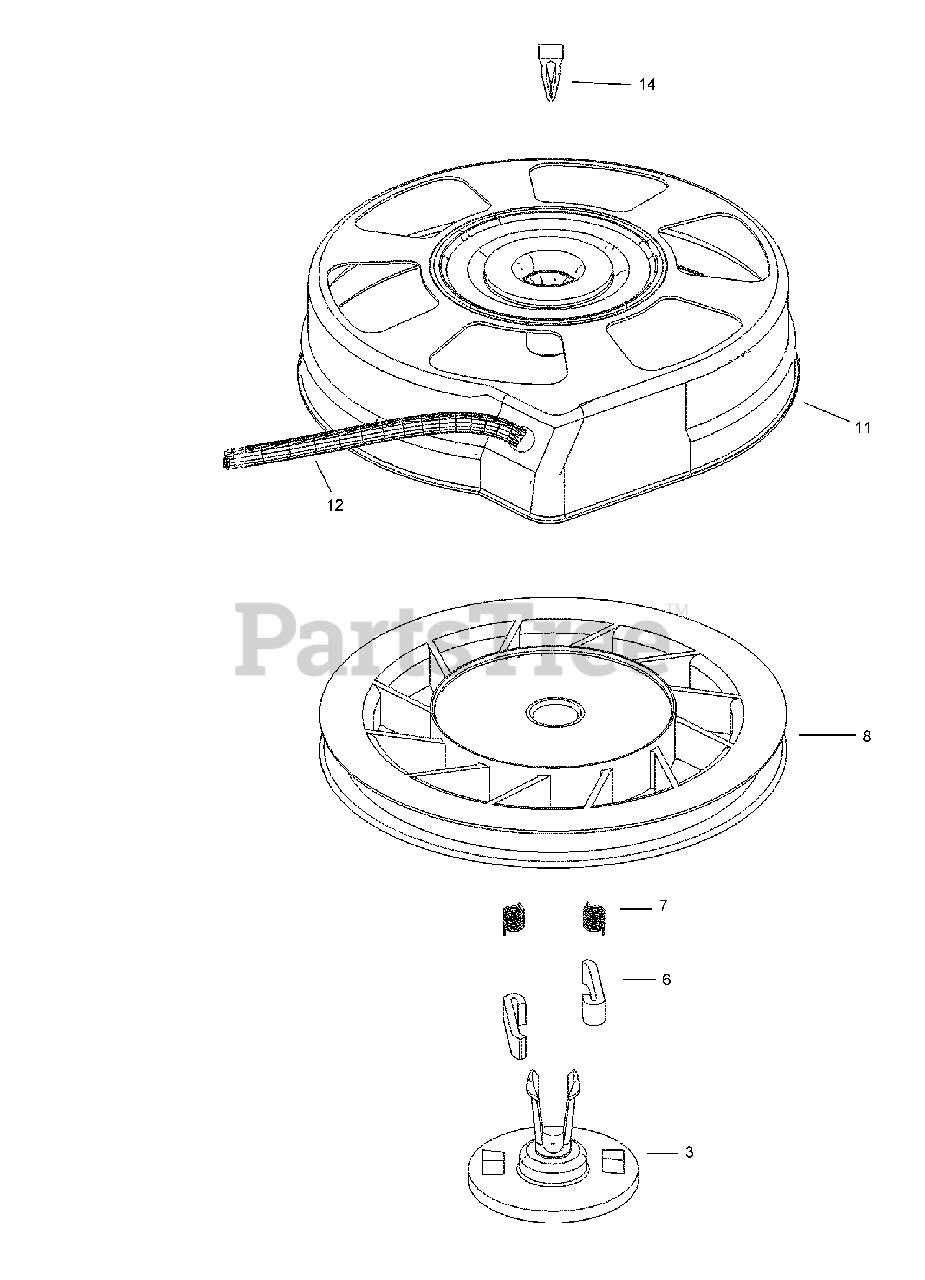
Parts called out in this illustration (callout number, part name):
3	Retainer
6	Dog-Starter
7	Spring-Dog
8	Pulley and Rewind Spring ASM
11	Starter Housing ASM
12	98 Starter Rope (cut to length)
14	Clip-Spring
